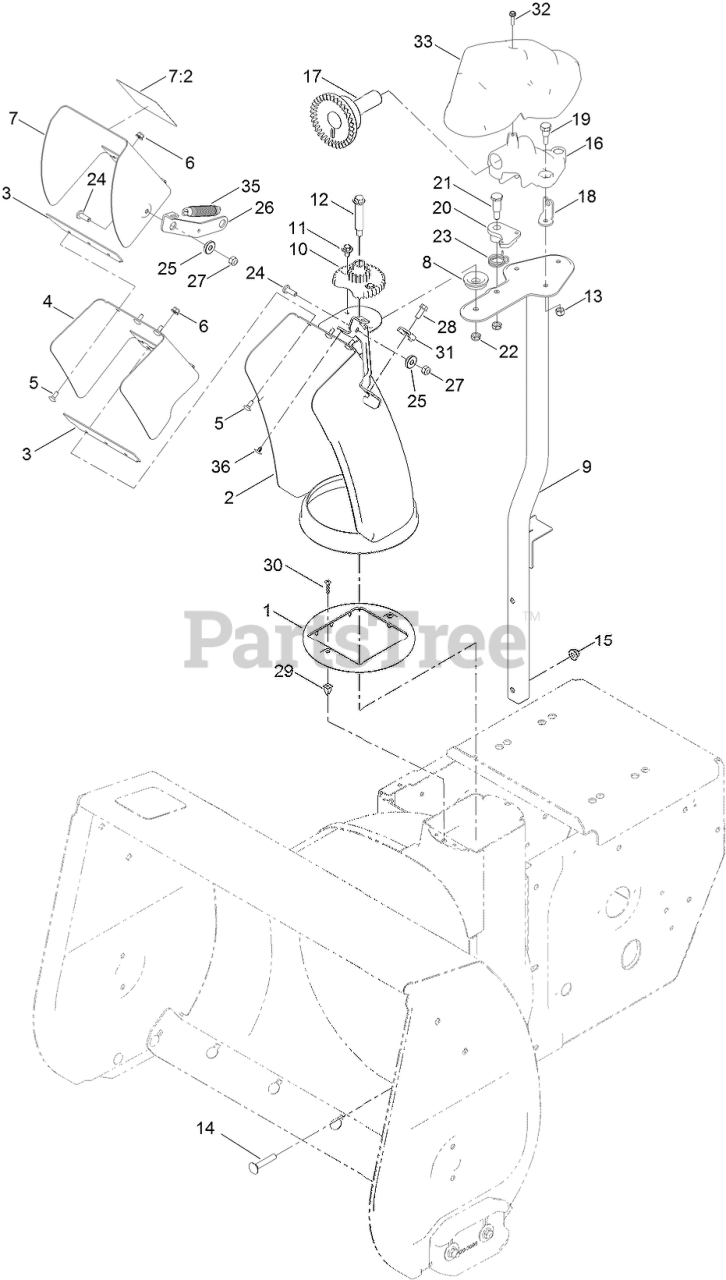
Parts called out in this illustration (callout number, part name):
1	GUIDE-CHUTE
2	LOWER CHUTE ASM
3	GASKET-DEFLECTOR
4	MIDDLE DEFLECTOR ASM
5	BOLT-CARR
6	NUT-HF
7	DEFLECTOR ASM
7:2	DECAL-DANGER
8	SPACER-CHUTE
9	CHUTE POST ASM
10	GEAR-CHUTE
11	SCREW AND WASHER ASM
12	BOLT-SHOULDER
13	NUT-HEX
14	BOLT-CAR
15	NUT-HF
16	MOUNT-GEAR, FACE
17	GEAR-FACE
18	ANCHOR-CABLE
19	SCREW-SHOULDER
20	LATCH-CHUTE
21	SCREW-SHOULDER, HH
22	NUT-HEX
23	SPRING-TORSION
24	SCREW-PH
25	BUSHING-PIVOT
26	LINK-DEFLECTOR
27	NUT-HEX
28	SCREW-HWH
29	GROMMET-SCREW
30	SCREW-PPH
31	CLAMP-CABLE
32	SCREW-PLASTITE, HWH
33	COVER-GEAR, FACE
35	SPRING-EXTENSION
36	PLUG-PLASTIC
